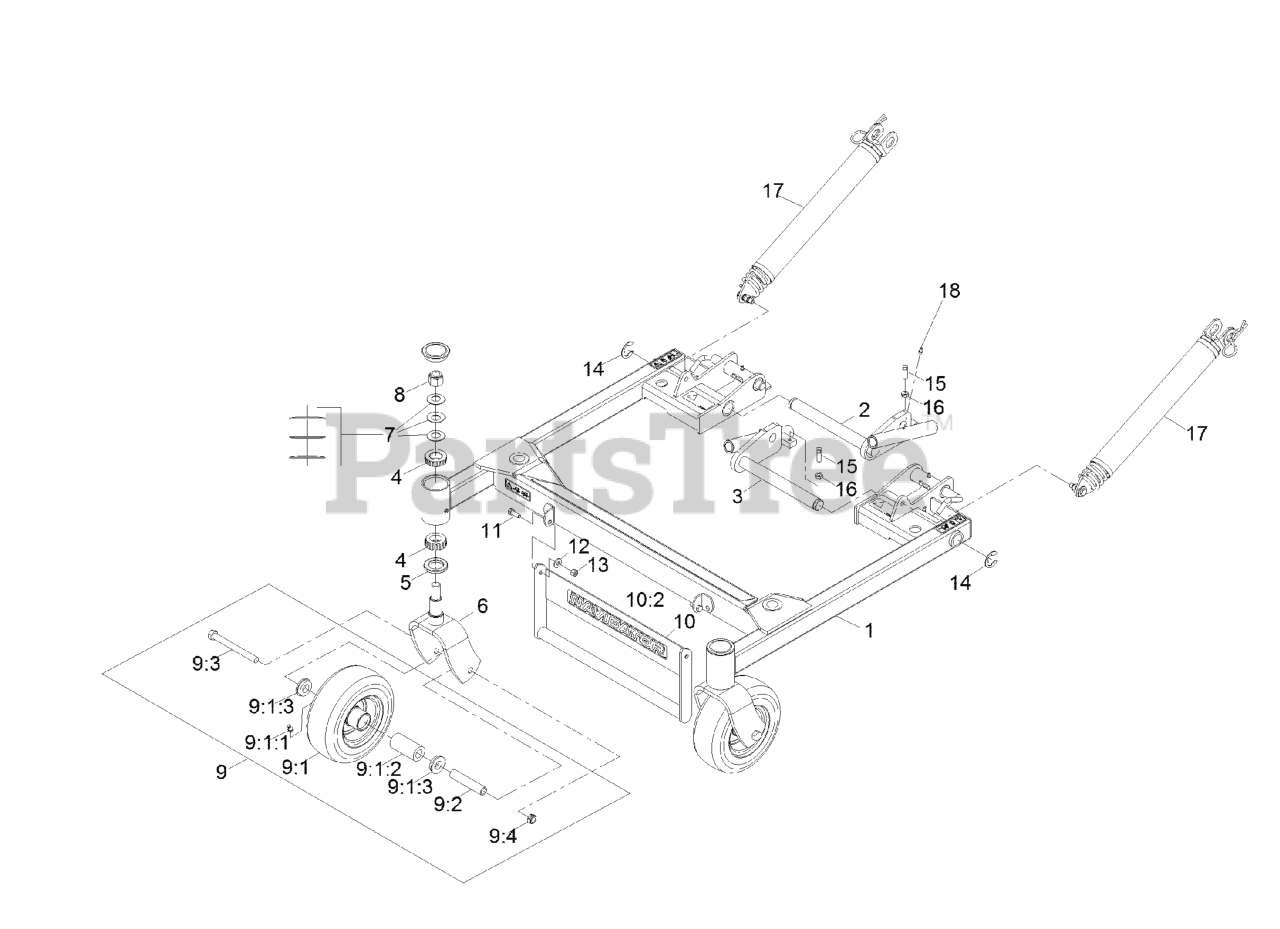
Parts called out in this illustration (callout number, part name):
1	DECK SUPPORT ASM
2	PIVOT-DECK, RH
3	PIVOT-DECK, LH
4	Cone-Bearing Tapered Roller
5	SEAL-GREASE
6	FORK-CASTER
7	WASHER-BELLVILLE
8	NUT-LOCK, NI
9	ASM,FF CASTER WHEEL W/AXL
9:1	ASM,WHEEL,TIRE & BRGS 8X3
9:1:1	FITTING-GREASE
9:1:2	BEARING-ROLLER, STRAIGHT
9:1:3	BUSHING
9:2	SPACER-CASTER, FRONT
9:3	SCREW-HH
9:4	NUT-HEX
10	ASM,DECK LIFT HANDLE W/DE
10:2	Decal-Navigator Logo
11	SCREW-HH
12	WASHER-SPRING
13	NUT-LOCK, NI
14	RING-SNAP
15	SCREW-SET, SQH
16	NUT-JAM
17	LIFT ASSIST SPRING ASM
18	FITTING-GREASE
